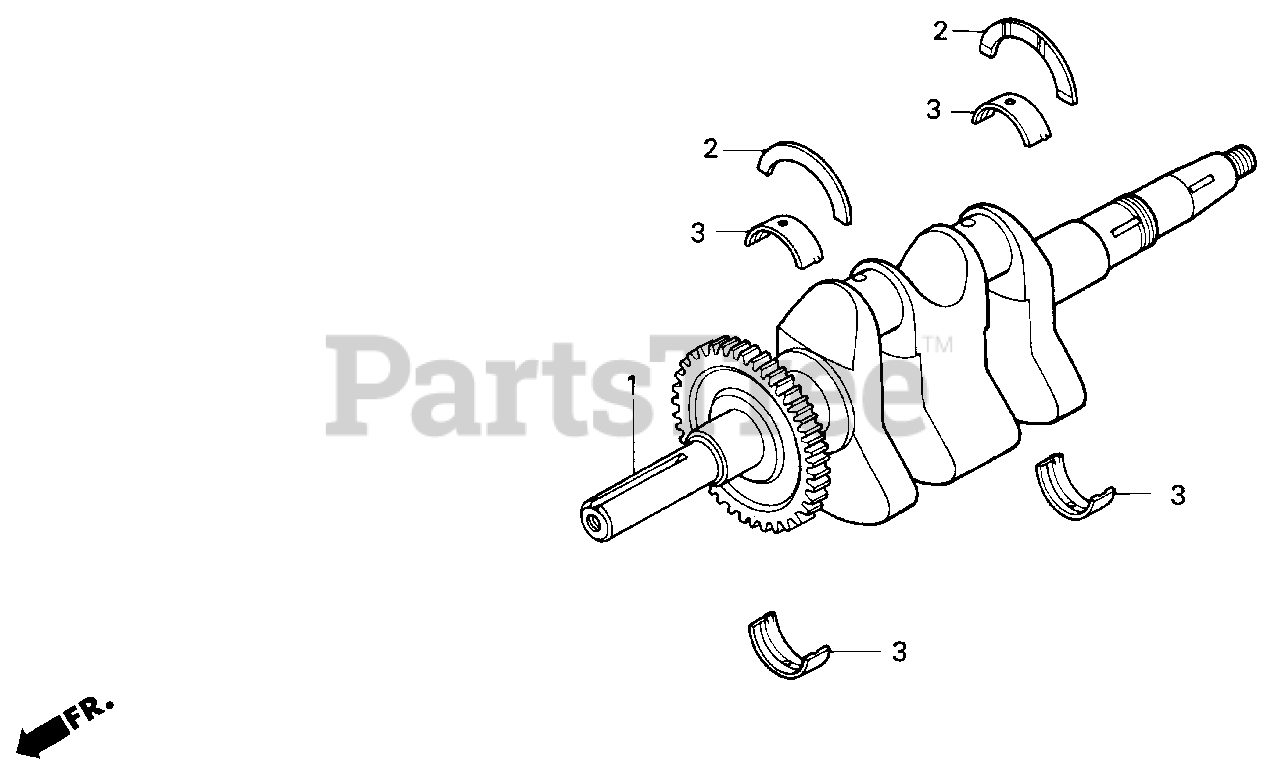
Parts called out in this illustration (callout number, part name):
1	CRANKSHAFT
2	BEARING, CRANKSHAFT THRUST
3	BEARING, CRANKSHAFT (1) (BLACK)
3	BEARING, CRANKSHAFT (2) (BROWN)
3	BEARING, CRANKSHAFT (3) (GREEN)
3	BEARING, CRANKSHAFT (4) (YELLOW)
3	BEARING, CRANKSHAFT (5) (RED)
